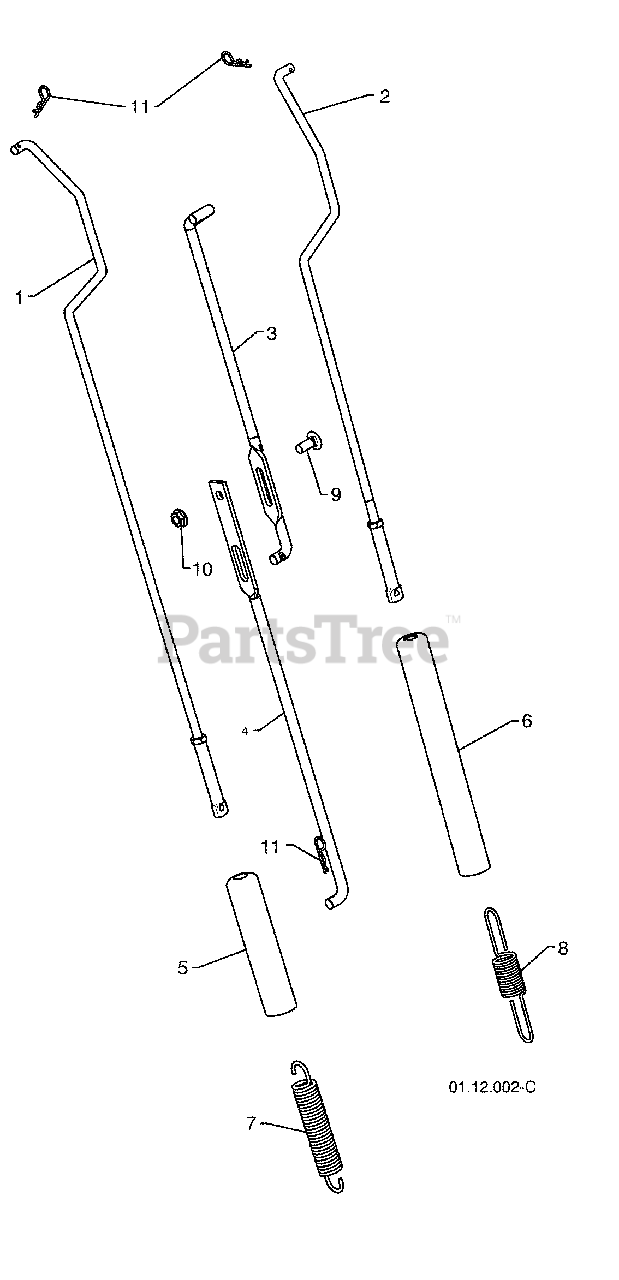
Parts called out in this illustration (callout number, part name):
1	IMPELLER ROD ASSEMBLY
2	TRACTION ROD ASSEMBLY
3	SHIFTER ROD TOP
4	SHIFTER ROD BOTTOM
5	SPRING SLEEVE
6	SPRING SLEEVE
7	IMPELLER SPRING
8	TRACTION SPRING
9	CARRIAGE BOLT 5/16-18 X .750
10	NUT 5/16-18
